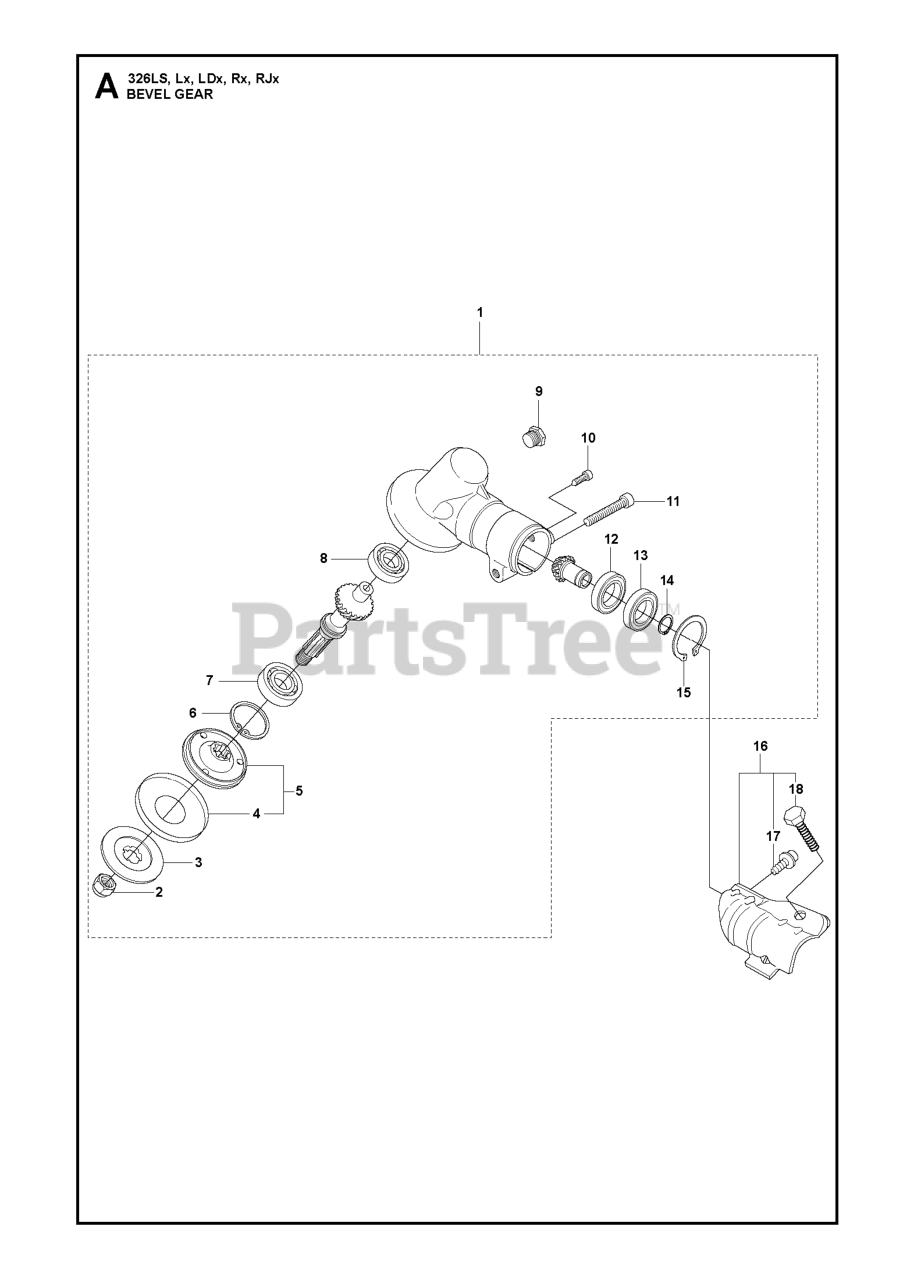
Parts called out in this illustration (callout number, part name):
1	GEARHEAD
2	GEARHEAD NUT - BRUSHCUTTER
3	SUPPORT FLANGE
4	WASHER
5	DRIVE DISC
6	RETAINING RING SGH 28
7	BEARING
8	BALL BEARING 8X22X7/608Z
12	BALL BEARING 24X9X1/609ZR
14	RETAINING RING
15	RETAINING RING
16	CLAMP
18	SCREW M6S 6X20
